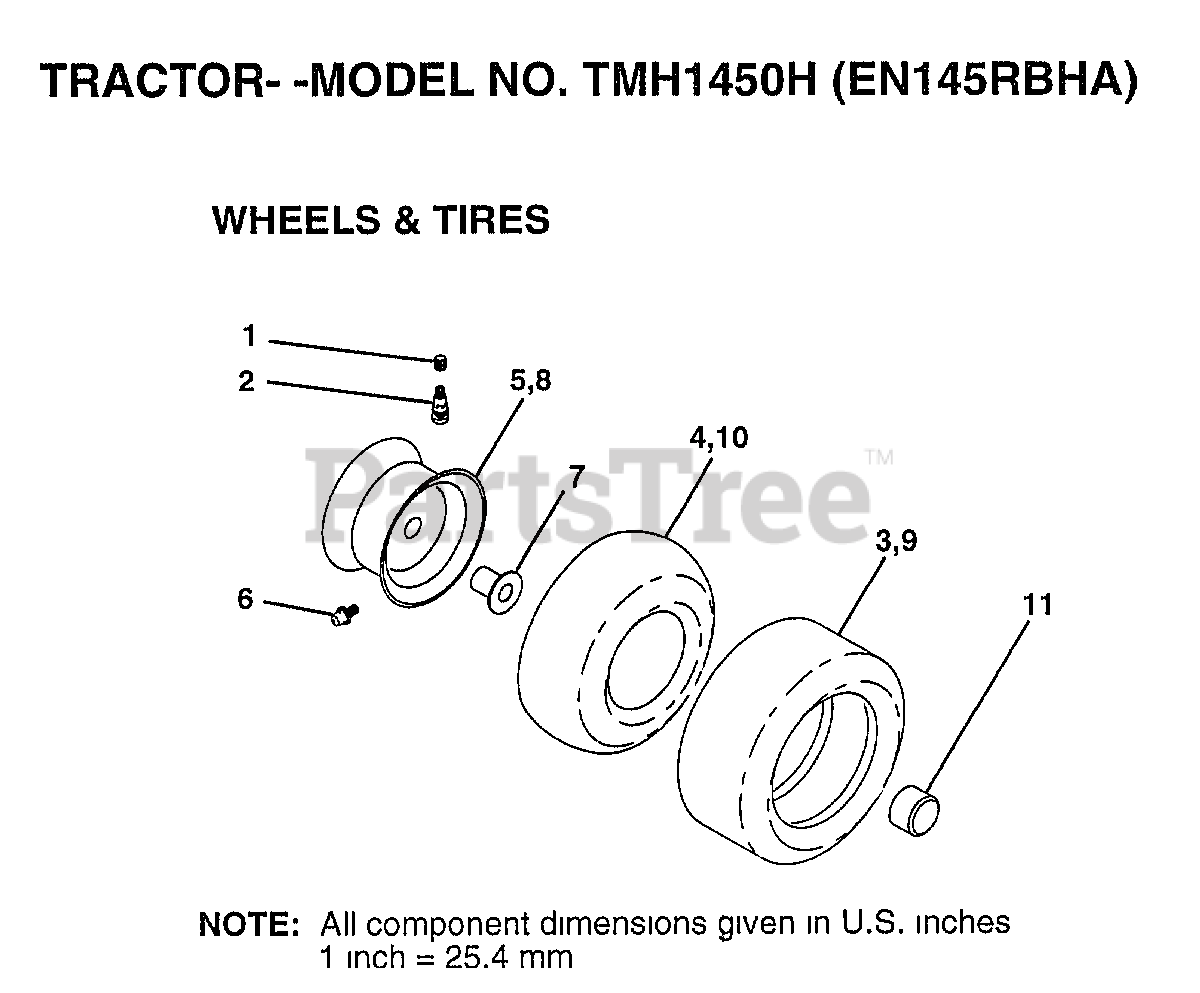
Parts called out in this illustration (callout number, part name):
1	VALVE CAP
2	VALVE STEM LT
4	TUBE.5.3/4.5/6
5	RIM.FRONT.6.YELLO
6	FITTING LT
7	"FLANGE, BEARING"
9	TIRE.20X8-8
10	TUBE.18X9.5-8
11	HUB CAP
